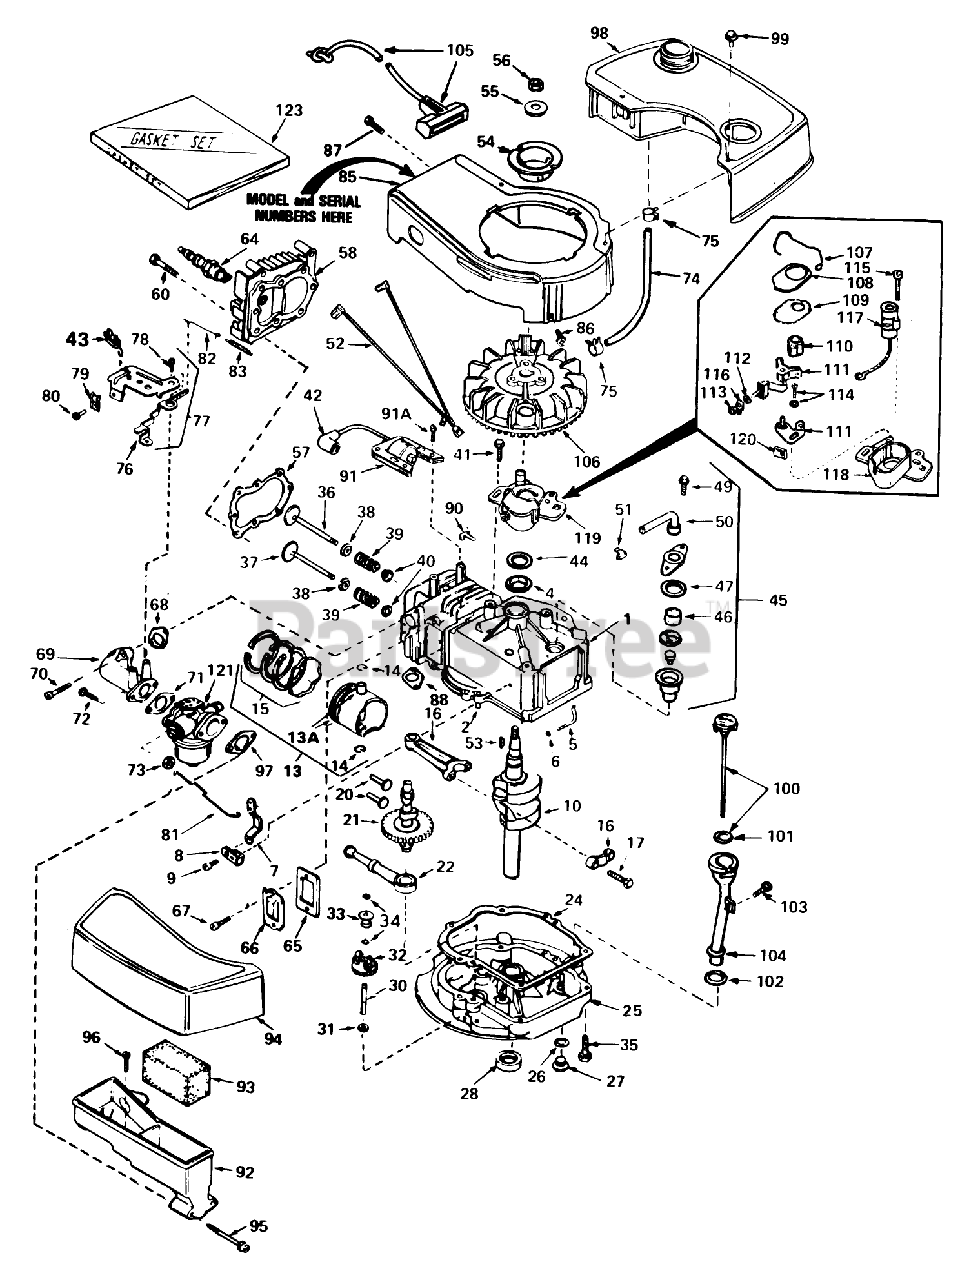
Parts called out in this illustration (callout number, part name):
1	Cyiinder Assy. (Incl. Ref. #2, 4 105)
2	Pin-Dowel
4	Seal-Oil
5	Rod, Governor (Incl. No. 36)
6	Washer-Flat
7	Governor Lever
8	Clamp-Lever, Governor
9	Screw
10	Crankshaft
13	Piston, Pin Ring Assy. (Std.)(Incl. Ref. #13A, 14 15)
13	Piston,Pin Ring Assy. (.010 over-size)(Incl. Ref. #13A, 14 15)
13	Piston, Pin Ring Assy. (Incl. Nos. 13A, 14 15)(.020 oversize)
13A	Piston Pin Assy. (Incl . Ref. . #14) (Std.)
13A	Piston Pin Assy. (Incl. Ref. #14) (.010 Oversize)
13A	Piston Pin Assy. (.020 oversize) (Incl. Ref. #14)
14	Ring-Retaining, Piston Pin
15	Ring Set Piston (Std.)
15	Ring Set Piston (.010 Oversize)
15	Ring Set Piston (.020 Oversize)
16	Rod Assy., Connecting (Incl. Ref. #17)
17	Bolt-Rod, Connecting
20	Lifter-Valve
21	Camshaft(Mech.Comp. Release)
22	Oil Pump ASM
24	Gasket, Mounting
25	Flange Assy., Mounting (Incl. Ref. #26thru 30)
26	Gasket-Oil Drain
27	Plug Oil Drain
28	Seal Oil
30	Shaft-Governor
31	Washer-Flat
32	Governor Gear ASM
33	Spool-Governor
34	Ring-Retaining
35	Screw (1/4-20 x 1-1/4)
36	Valve, Intake (Incl. Ref. #38, 39 40) (Std.)
36	Valve, Exhaust (1/32" Oversize) (Incl. Nos. 8, 9 10)
37	Valve, Exhaust (Standard) (Incl. Nos. 8, 9 10)
37	Valve, Exhaust (1/32" Oversize) (Incl. Nos. 8, 9 10)
38	Cap-Upper Valve Spring
39	Spring-Valve
40	Cap-Valve, Spring
41	Screw
42	Cover-Spark Plug
43	Terminal
44	Gasket Stator
45	Breather Assy. (Incl. Ref. #46, 47, 49, 50 51 )
46	Element-Breather
47	Gasket-Breather
49	Screw (10-24 x 9/16)
50	Tube, Breaker
51	Clip, Breather
52	Wire Ground
53	682488 LB GRASS HI-
54	Hub-Starter
55	Washer-Belleville
56	Nut-Flywheel
57	63573 GIL 42 SNWTHW
58	Head-Cylinder
60	Screw (5/16-18x1-1/2)
64	Plug, Spark (J17LM or equiv.)
64	Plug, Spark (Champion RCJ-8)
65	Gasket-Breather
66	Cover-Valve
67	Screw
68	Gasket-Intake
69	Pipe, Intake (Incl. No. 68)
70	Screw (1/4-20 x 1)
71	Gasket-Carburetor
73	Nut and Lock Washer (1/4-28)
74	Line-Fuel
75	Clamp-Line, Fuel
76	Lever Control
77	Control Assy., Speed (Incl. Nos, 76, 78 89)
78	Screw, Hex Washer Hd Shoulder Self-Tap
79	Conduit
80	Screw (10-32 x 3/8)
81	Link-Throttle
82	Link Governor Spring
83	Spring Governor
85	Housing Blower
86	Screw
87	Screw (10-24 x 9/16)
88	Gasket Exhaust
90	Clip-Wire
91	Lamination Coil Assy. (Incl. No. 42)
91A	Screw
92	Body Air Cleaner
93	Filer, Air
94	Cove, Air Cleaner
95	Screw Fil Hd.
96	Screw, Hex Hd.
97	Gasket-Air Cleaner
98	Tank, Fuel
99	Screw (10-32 x 35/64)
100	Dipstick, Oil (Incl. Ref. #101)(Twist Lock)
101	O-Ring
102	Gasket
103	Screw (10-32 x 1/2)
104	Tube-Oil Fill
105	Rope Assy., Starter
106	FIywheel
107	Spring Breaker Box
108	Cover-Dust
109	Gasket-Dust Cover
110	Cam-Breaker
111	Breaker Assy.
112	Washer
113	DECAL
114	Breaker Screw
115	Condenser Screw
116	Terminal, Ground
117	Condenser
118	Stator Plate
119	Stator Plate Assy. (incl. Nos. 107, 111 thru 118 120)
120	Felt,Cam Wiper
121	Carburetor (Incl. Ref. #71 )
123	Gasket Set
